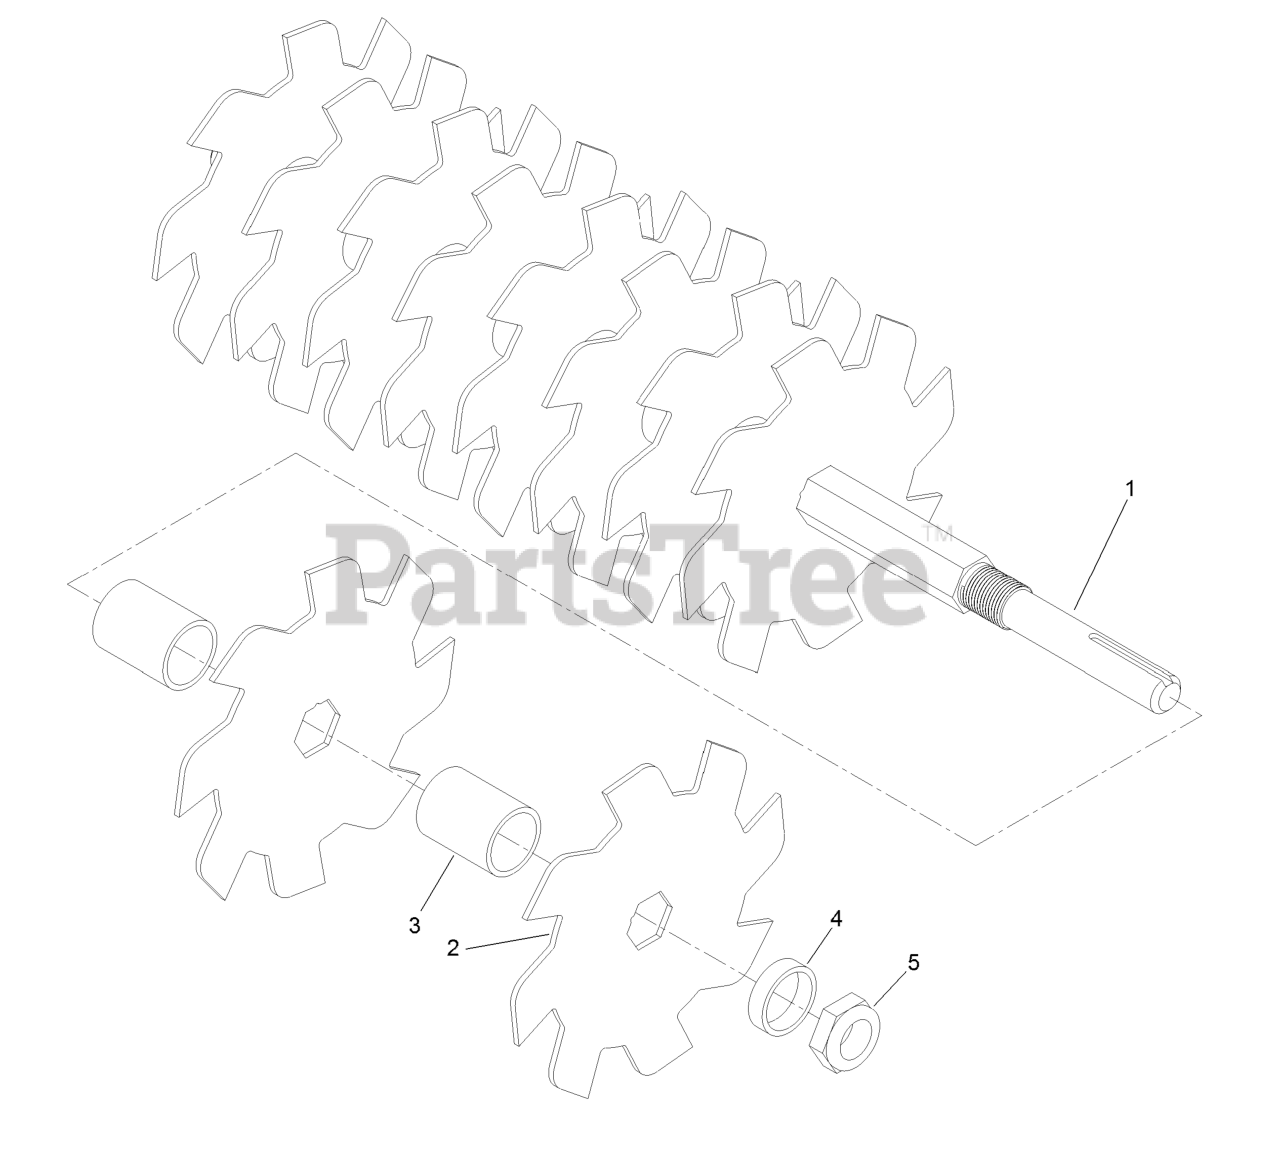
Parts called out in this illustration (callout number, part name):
1	Shaft-Slicer
2	Blade-Cutting, Seeder
3	Spacer-Blade
5	Nut-Lock, NI
